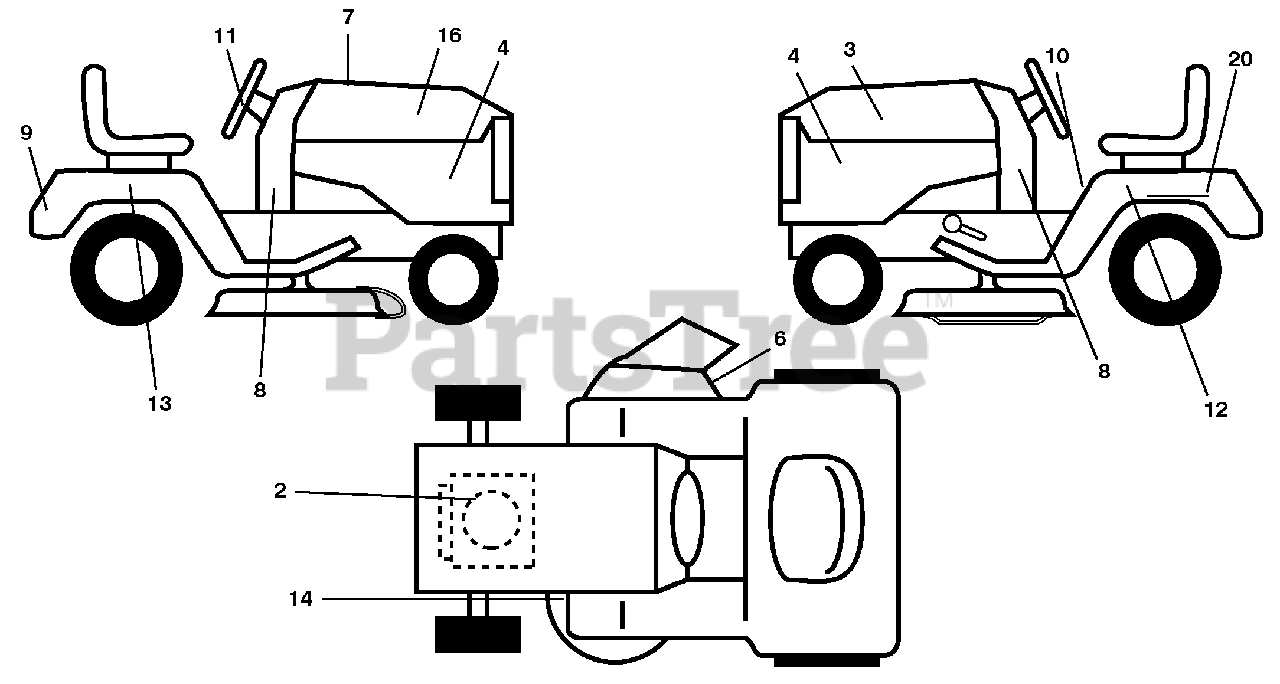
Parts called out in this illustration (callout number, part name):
2	Decal Engine H.P.
3	Decal Hood LH
4	Decal Side Panel
6	Decal Warning, Keep Hand Away
7	Decal Replacement Parts
8	Decal LWRDASH
9	Decal Fender Logo
10	Decal Fender Warning
11	Decal Ins. Strg. Whl.
12	Decal Fender SD LH
13	Decal Fender SD RH
14	Decal V-Belt Schematic
16	Decal Hood RH
20	Decal Bat. Dan./Poi.
